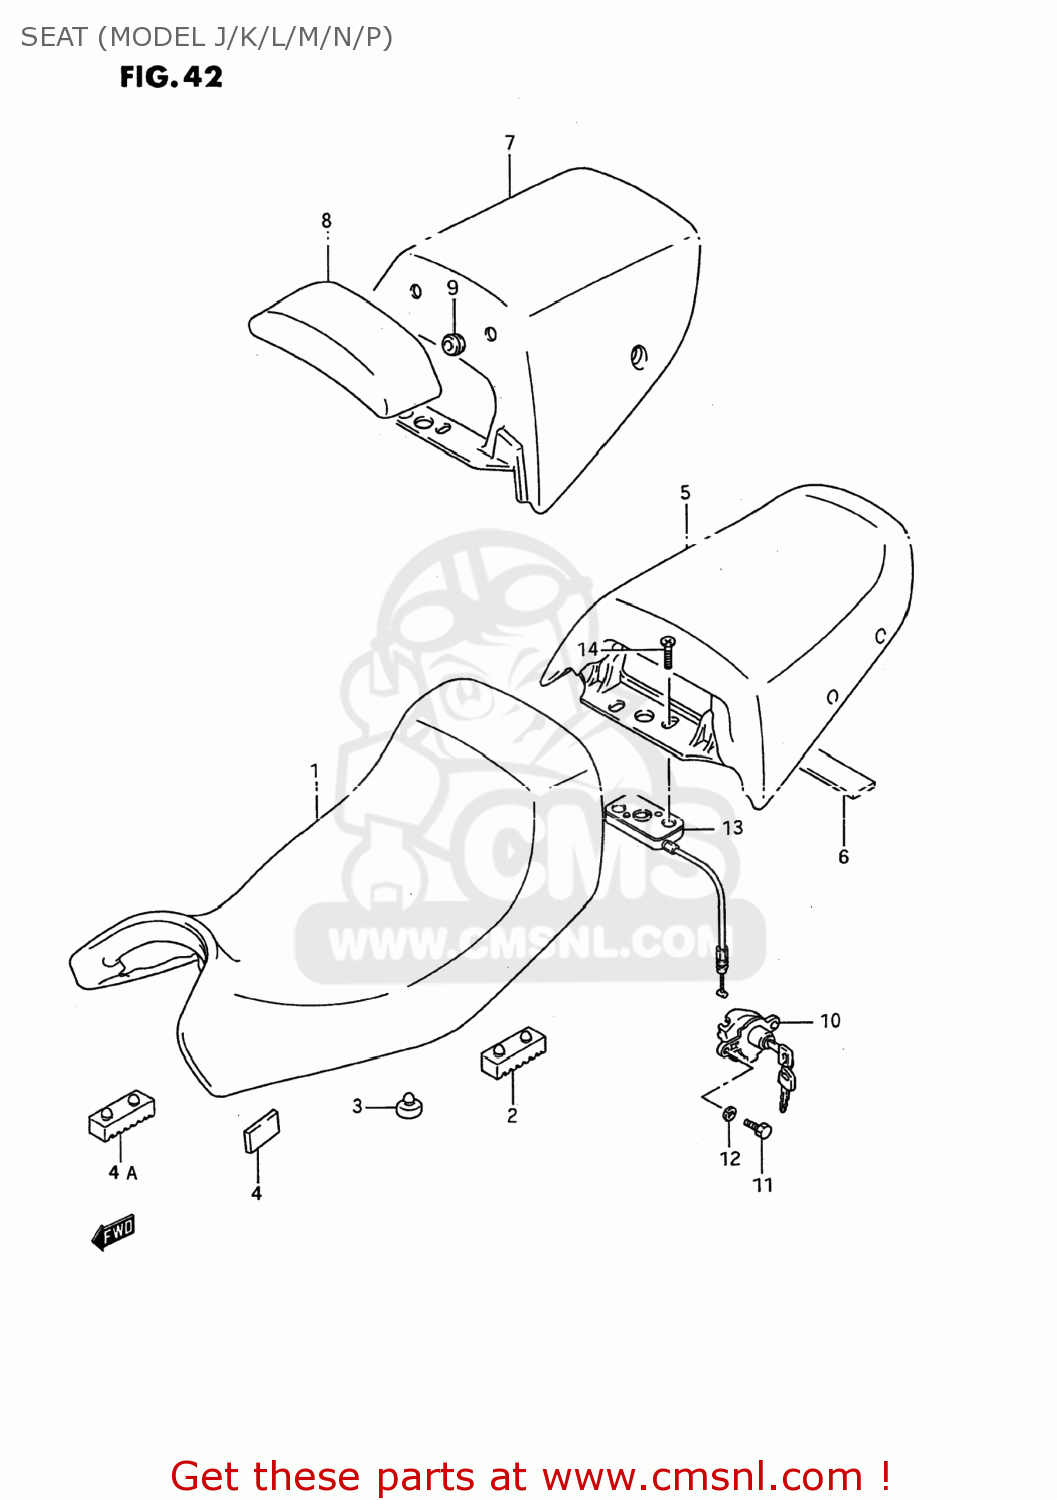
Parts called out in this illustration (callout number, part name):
1	SEAT SET
2	CUSHION,SEAT
3	CUSHION
4	CUSHION,FRONT
4A	CUSHION,SEAT(40X20X15)
5	SEAT SET,PILLION
6	CUSHION,PILLION SEAT,REAR
7	SEAT TAIL COVER WITH PILLION
8	PAD ASSEMBLY,TAIL COVER (O
9	CUSHION
10	LOCK SET,SEAT
11	BOLT
12	WASHER,LOCK
13	BRACKET,SEAT SUPPORT RR
14	SCREW
